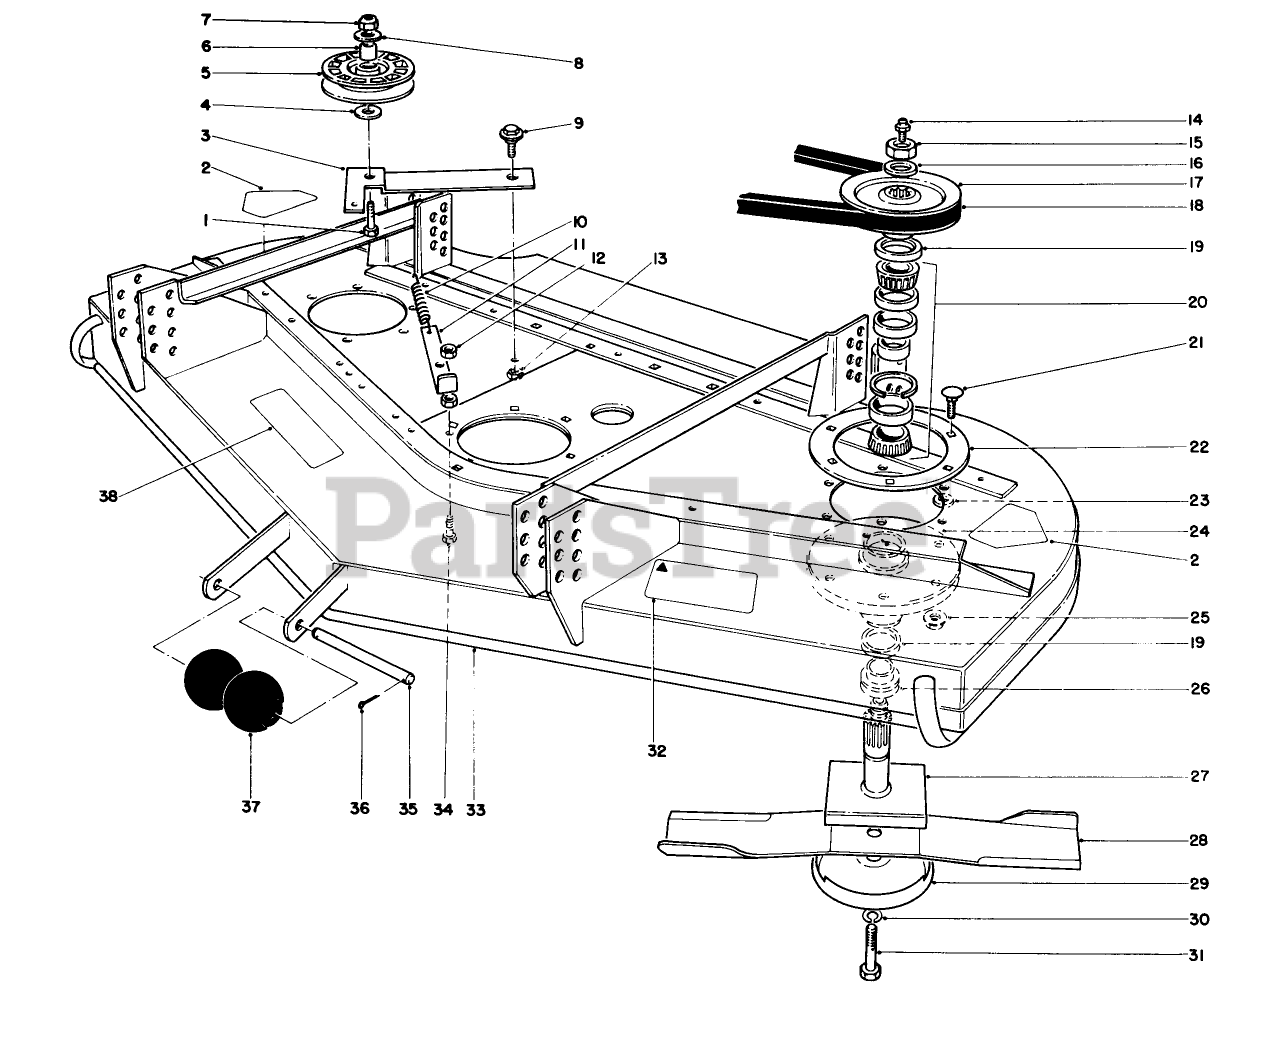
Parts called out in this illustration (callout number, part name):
1	SCREW-HH
2	DECAL-DANGER
6	Bushing
7	NUT-LOCK, NI
8	Washer
9	SCREW-SHOULDER
10	SPRING-EXTENSION, DECK
12	NUT-LOCK, CONE
13	NUT-LOCK, NI
14	FITTING-GREASE
15	NUT-HEX
16	WASHER
18	V-BELT, DECK
19	SEAL-OIL
20	BEARING ASM
21	SCREW-CARR
23	WASHER-FLAT
25	NUT-HF
26	SPACER
27	SHAFT
30	WASHER-LOCK
31	SCREW-BLADE
34	SCREW-HH
35	SHAFT-ROLLER
36	PIN-COTTER
37	ROLLER
